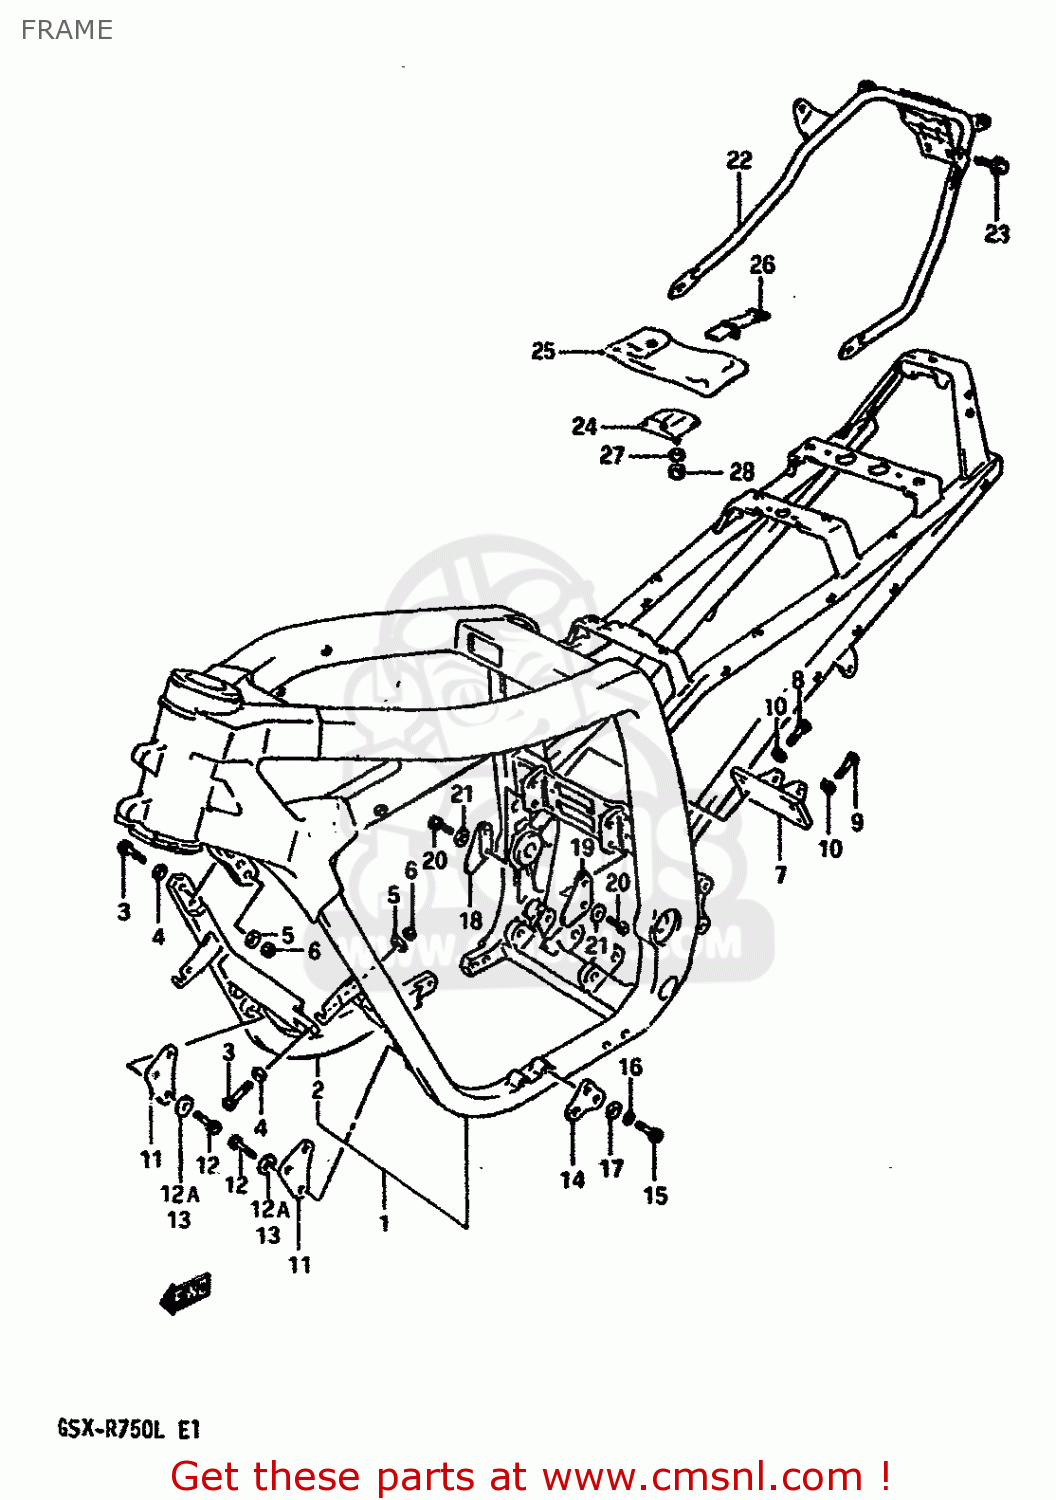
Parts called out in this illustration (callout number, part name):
1	FRAME
2	TUBE,FRAME
3	BOLT
4	WASHER (10.1X21X2.3)
5	WASHER
6	NUT
7	BRACKET,RCU
8	BOLT 10X27
9	BOLT
10	WASHER
11	PLATE,ENGINE MOUNTING
12	BOLT, FRONT LH
12A	WASHER,LOCK
13	WASHER (8.2X20X1.6)
14	PLATE,ENGINE MOUNT NO.2
15	BOLT, FRONT LH
16	WASHER,LOCK
17	WASHER (8.2X20X1.6)
18	PLATE,ENGINE MOUNTING NO
19	PLATE,ENGINE MOUNTING NO
20	BOLT(8X22)
21	WASHER (8.2X20X1.6)
22	GRIP COMP,REAR
23	BOLT
24	HOLDER,TOOL
25	TOOL ASSY
26	BAND
27	WASHER
28	NUT 6MM
